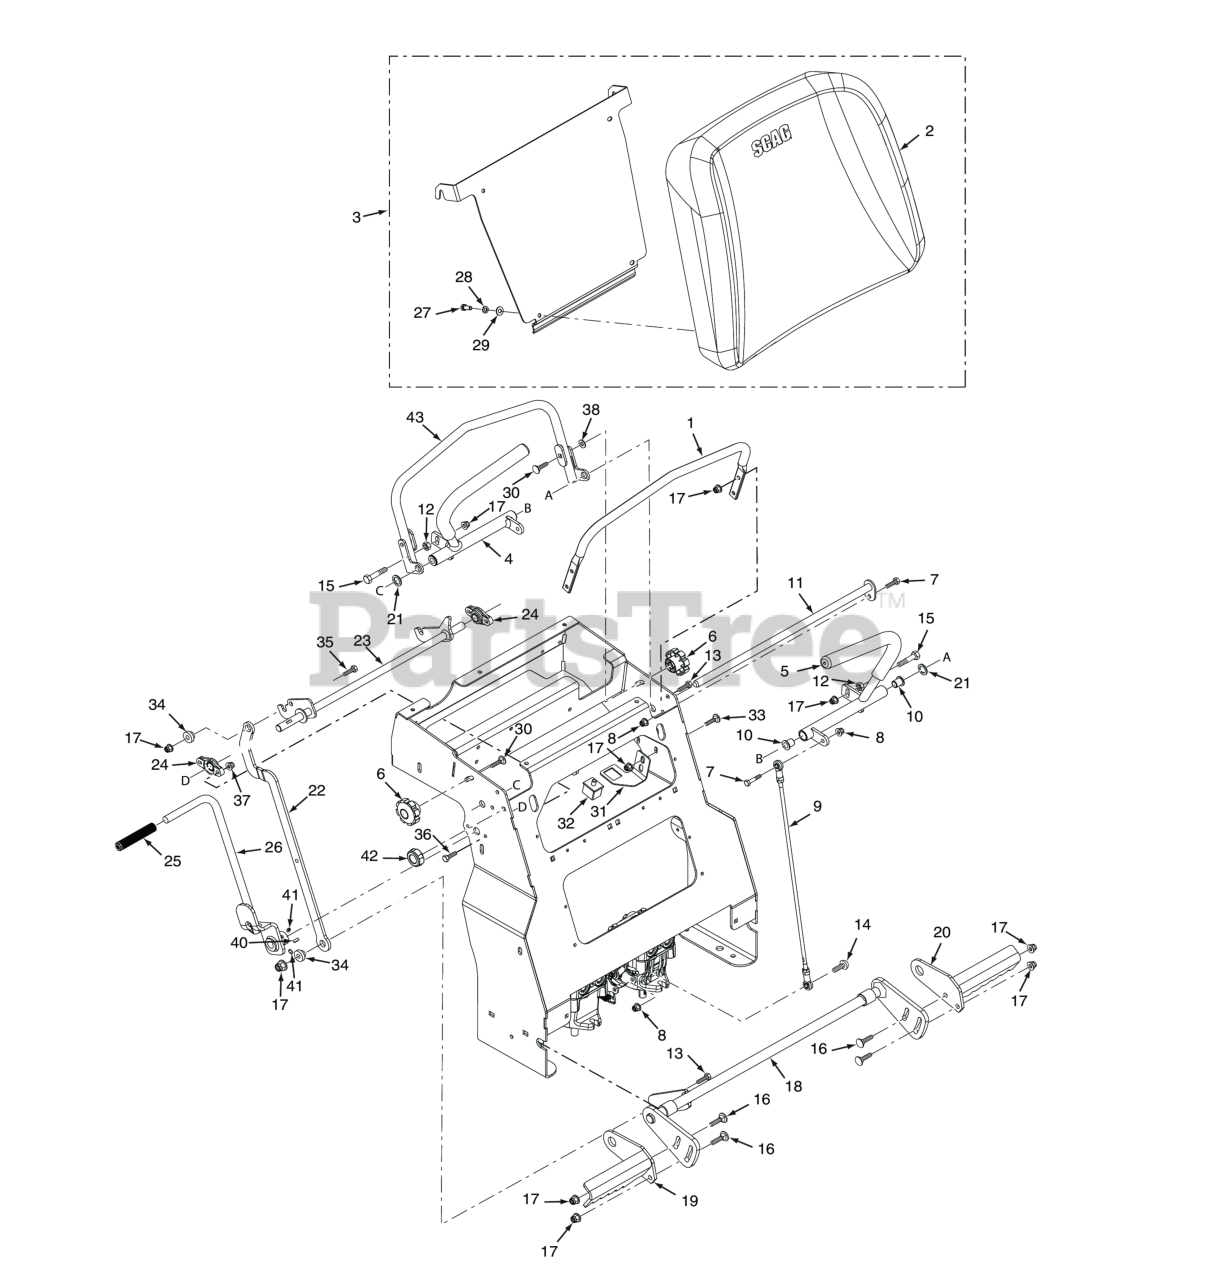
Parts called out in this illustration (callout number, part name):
1	Reference Bar
2	Operator Pad
3	Operator Pad Assy., w/Decal
4	Handlebar Assembly, LH
5	Handlebar Assembly, RH
6	Knob, 5/16 - 18
7	Bolt, Hex 5/16" - .375 x 1.00- Stainless Steel
8	Locknut, 5/16-18 Flg. Elastic Stop - Stainless Steel
9	Linkage Assy., Steering
10	Bearing, .625 ID Plastic
11	Shaft Weldment, Control Arm
12	Nut, 3/8 - 16 - Stainless Steel
13	Bolt, Hex Head 3/8 - 16 x 1.50 - Stainless Steel
14	Hex Head Socket, 5/16-18 x 1" (36)
15	Bolt, Hex 3/8 - 16 x 1.75 - Stainless Steel
16	Bolt, Carriage 3/8 - 16 x 1.25 - Stainless Steel
17	Nut, Flange Elastic Stop 3/8 - 16 - Stainless Steel
18	Bellcrank Weldment, Brake
19	BRAKE PADDLE WLMT, LH
20	Brake Paddle Weldment, RH
21	Washer, Flat 5/8 - .687 x 1.00 x .078 - Stainless Steel
22	Link, Brake Engage
23	Lock Weldment, Neutral
24	Bearing
25	GRIP, PARKING BRAKE
26	Brake Lever Assembly
27	Bolt, Hex 5/16 - 18 x .75 - Stainless Steel
28	Washer, Lock 5/16 Spring - Stainless Steel
29	Washer, Flat 5/16 - .349 x .750 x .050 - Stainless Steel
30	Bolt, Carriage 5/16 - 18 x 1" - - Stainless Steel
31	Mounting Bracket, Brake Switch
32	Switch, Double Pole - Plunger
33	Bolt, Carriage 3/8-16 x 1.0 - Stainless Steel
34	BUSHING, BRONZE - .376 ID X .627 OD
35	Cap Screw, 3/8 - 16 x 1.25 Hex Socket - Stainless Steel
36	Bolt, Hex 1/4 - 20 x 1.25 - Stainless Steel
37	Locknut, 1/4 - 20 Flg. Elastic Stop - Stainless Steel
38	Washer, Flat 5/16 - .349 x .750 x .050 - Stainless Steel
39	Nut, Push On - Stainless Steel
40	KEY, WOODRUFF #61, 3/16 X 5/8
41	Set Screw, 1/4 - 20 x .25 - Stainless Steel
42	Knob, 5/16-18
43	Weldment, Reference Bar
